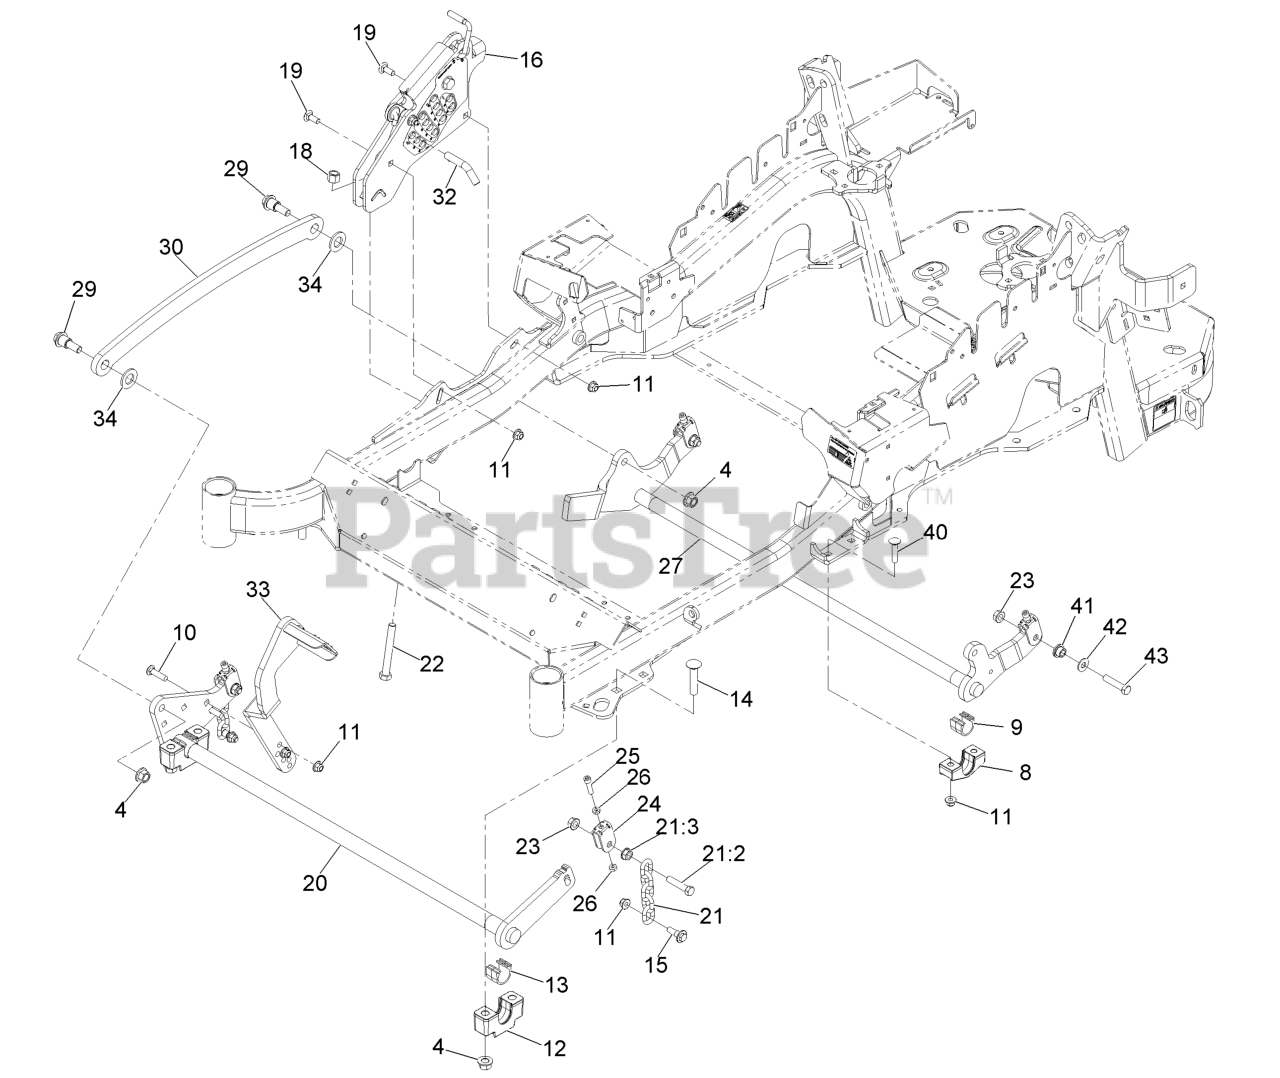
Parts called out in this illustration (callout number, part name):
4	Nut-Lock 1/2-13
9	BEARING-CROSS SHAFT, REAR
10	SCREW-CARR
11	NUT-HF, NI
12	SUPPORT-CROSS SHAFT, BEARING
13	BEARING-CROSS SHAFT, FRON
14	Bolt-Carriage 1/2-13 X 2 1/2 Spl Neck
15	SCREW-SHOULDER, HHF
16	HEIGHT-OF-CUT ASM
18	NUT-LOCK, NI
19	BOLT-CARR
21	DECK LIFT CHAIN ASM
21:2	SCREW-HH
22	BOLT-TAP
24	YOKE-ADJUST, DECK
25	SCREW-HSH
26	NUT-JAM
27	LIFT-DECK, REAR
29	SCREW-SHOULDER, HHF 1/2-13 X 1.12
30	LINK-LIFT, DECK
32	PIN-HOC
33	FOOT LEVER
34	WASHER-FLAT
40	SCREW-CARR
41	BUSHING-FLANGED
42	WASHER-FLAT
43	SCREW-HH
